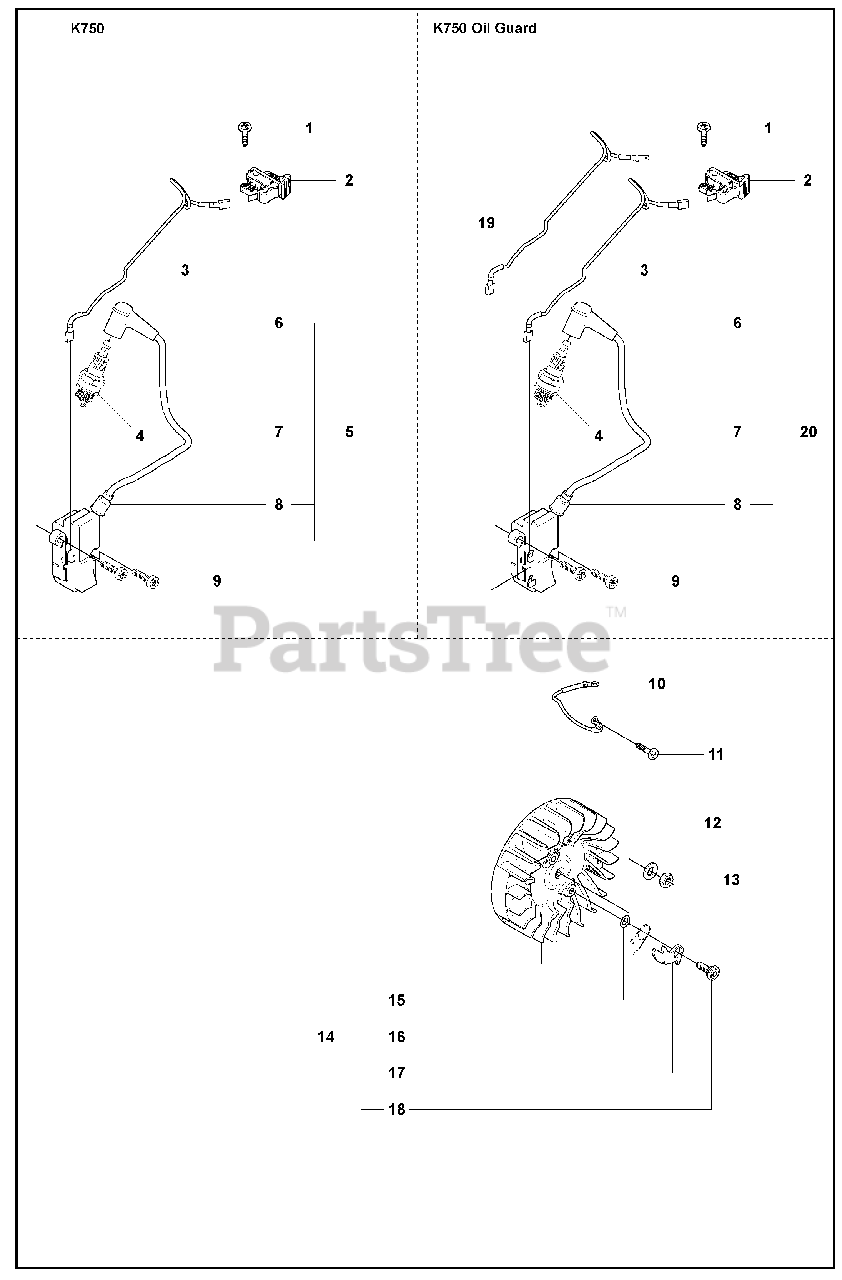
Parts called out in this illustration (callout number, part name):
2	STOP SWITCH
3	CABLE
4	SPARK PLUG
5	IGNITION MODULE
6	SPARK PLUG CAP
7	IGNITION CABLE
8	ISOLERHATT
12	WASHER STEEL
14	FLYWHEEL
15	WASHER STEEL
19	CABLE
20	IGNITION MODULE
